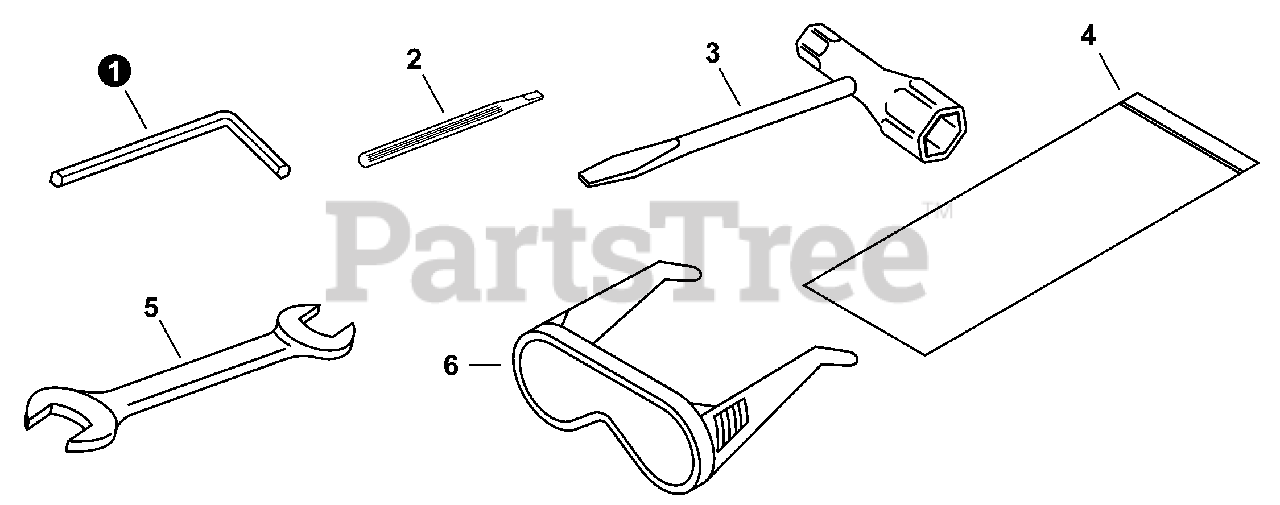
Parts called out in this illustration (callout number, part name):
1	WRENCH, ALLEN 4 MM
2	SCREWDRIVER, PLASTIC
3	T-WRENCH 13×19 MM
4	BAG, TOOL
5	SPANNER 8×10
6	GLASSES, SAFETY
